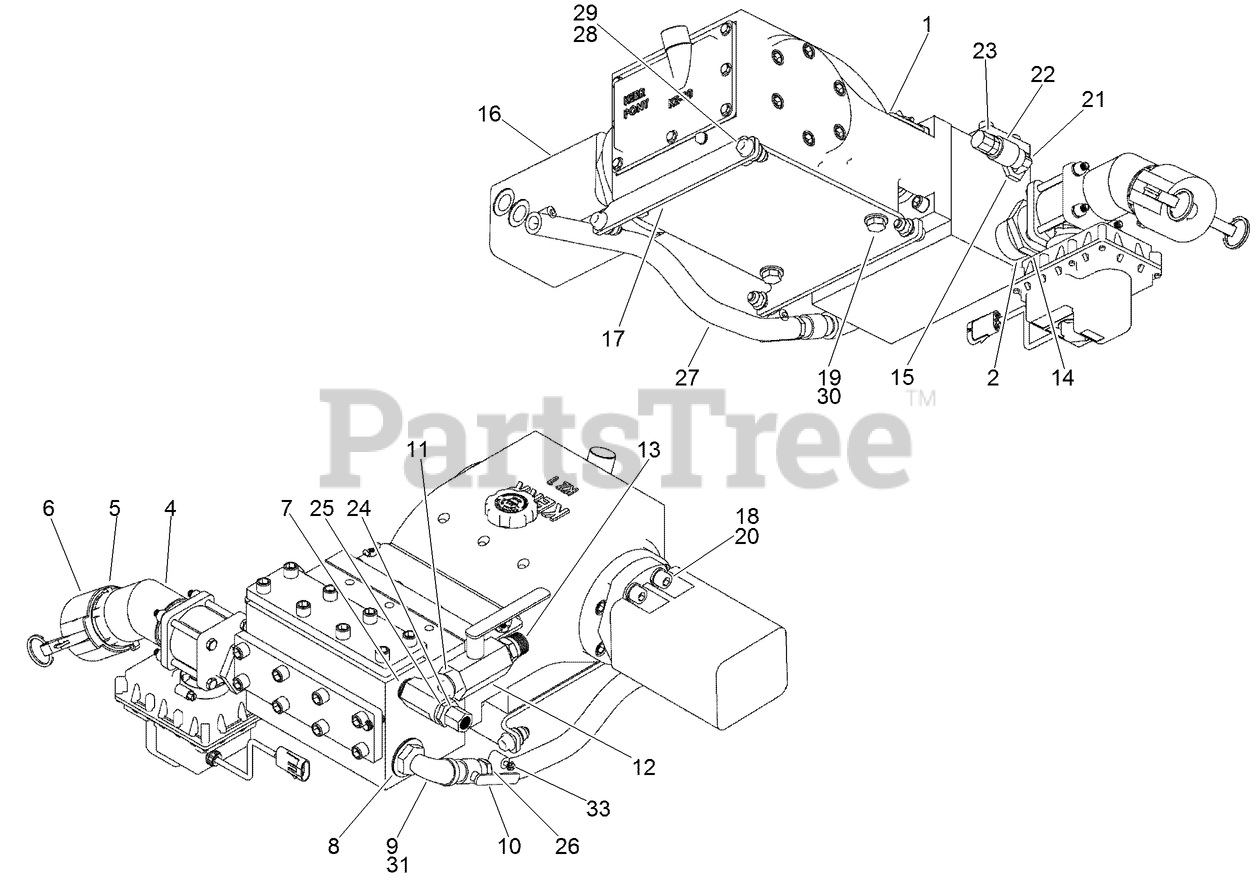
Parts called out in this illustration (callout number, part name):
1	MUD PUMP ASM
2	NIPPLE-PIPE
4	ELBOW-PIPE-45
5	ADAPTER-MALE
6	CAP-CONNECT, QUICK
7	FITTING-TEE
8	BUSHING-PIPE, REDUCER
9	FITTING - 90 Elb Pipe Street 1/2
10	VALVE-BALL
11	NIPPLE-STRAIGHT
12	VALVE-BALL
13	FITTING-STRAIGHT
14	BUSHING-REDUCER
15	BUSHING-REDUCER
16	HYD MOTOR ASM
17	PLATE - Mud Pump Mount
18	WASHER-0.531 x 1.062 x 0.092 in CST ZND
19	BOLT-HH
20	SCREW-HSH
21	FITTING-ELBOW-90
22	NIPPLE-CONNECT, QUICK
23	CAP-DUST, PLASTIC
24	BUSHING-REDUCER
25	FITTING-STRAIGHT
26	ADAPTER
27	HOSE - 5/8 x 131 in
28	SCREW-HH
29	NUT-FLANGE, NYLOCK
30	WASHER-Spring Lock Reg 1/2 ZND
31	NIPPLE-PIPE
33	CLAMP-HOSE
